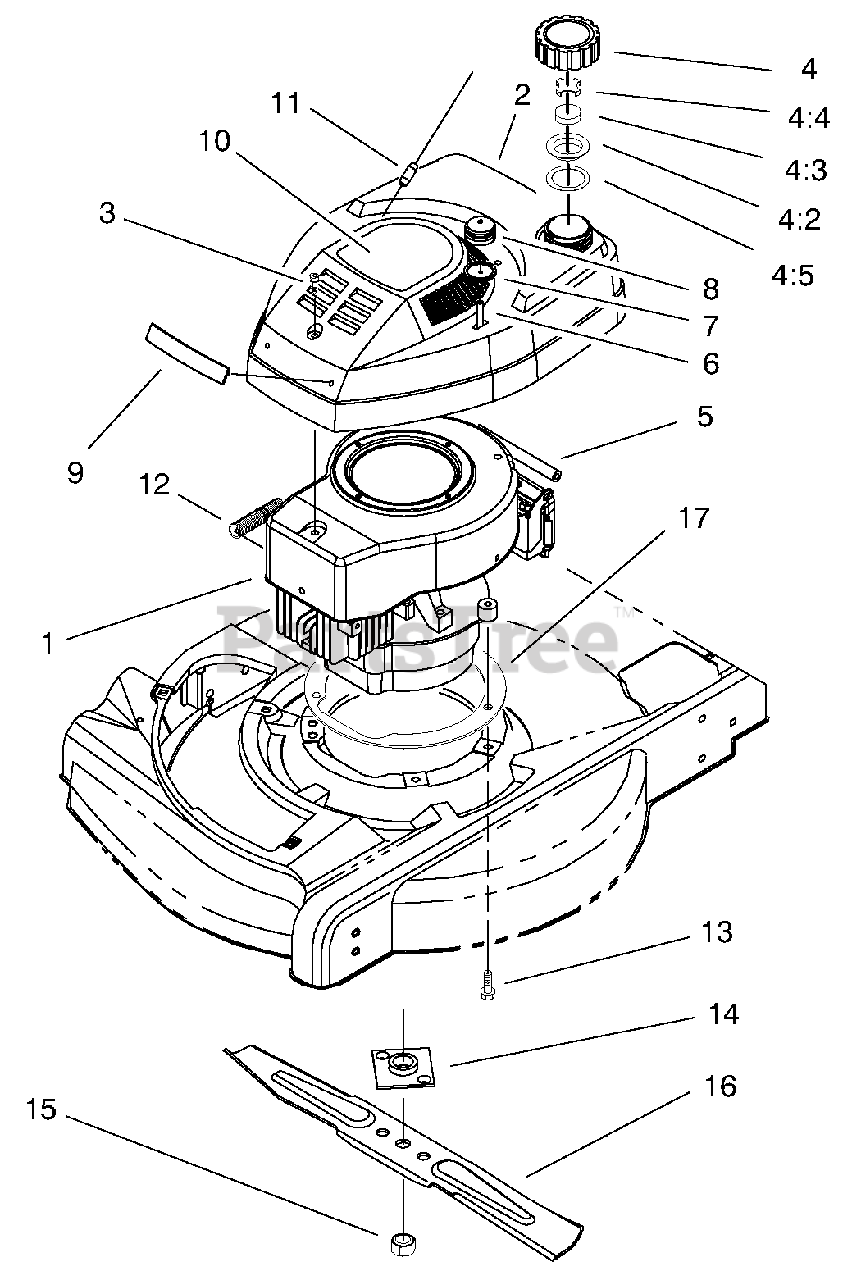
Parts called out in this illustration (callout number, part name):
1	ASM-Engine
2	ASM-Tank & Shroud
3	Screw-Sems
4	ASM-Fuel/Oil Cap
4:2	Cover-Fuel Cap Baffle
4:3	Foam Baffle
4:4	Baffle-Gas Cap
4:5	Gasket-Fuel Cap
5	Gas Line
6	Hose-Primer
7	Body-Primer
8	Bulb-Primer
9	Applique-Shroud
10	Decal-Shroud Top
11	Rope-Stop
12	Spring-Compression
13	Screw-Engine Mount
14	ASM-Plate & Collar
15	Blade-21" Whirl
16	Nut-Blade
17	Plate-Engine
